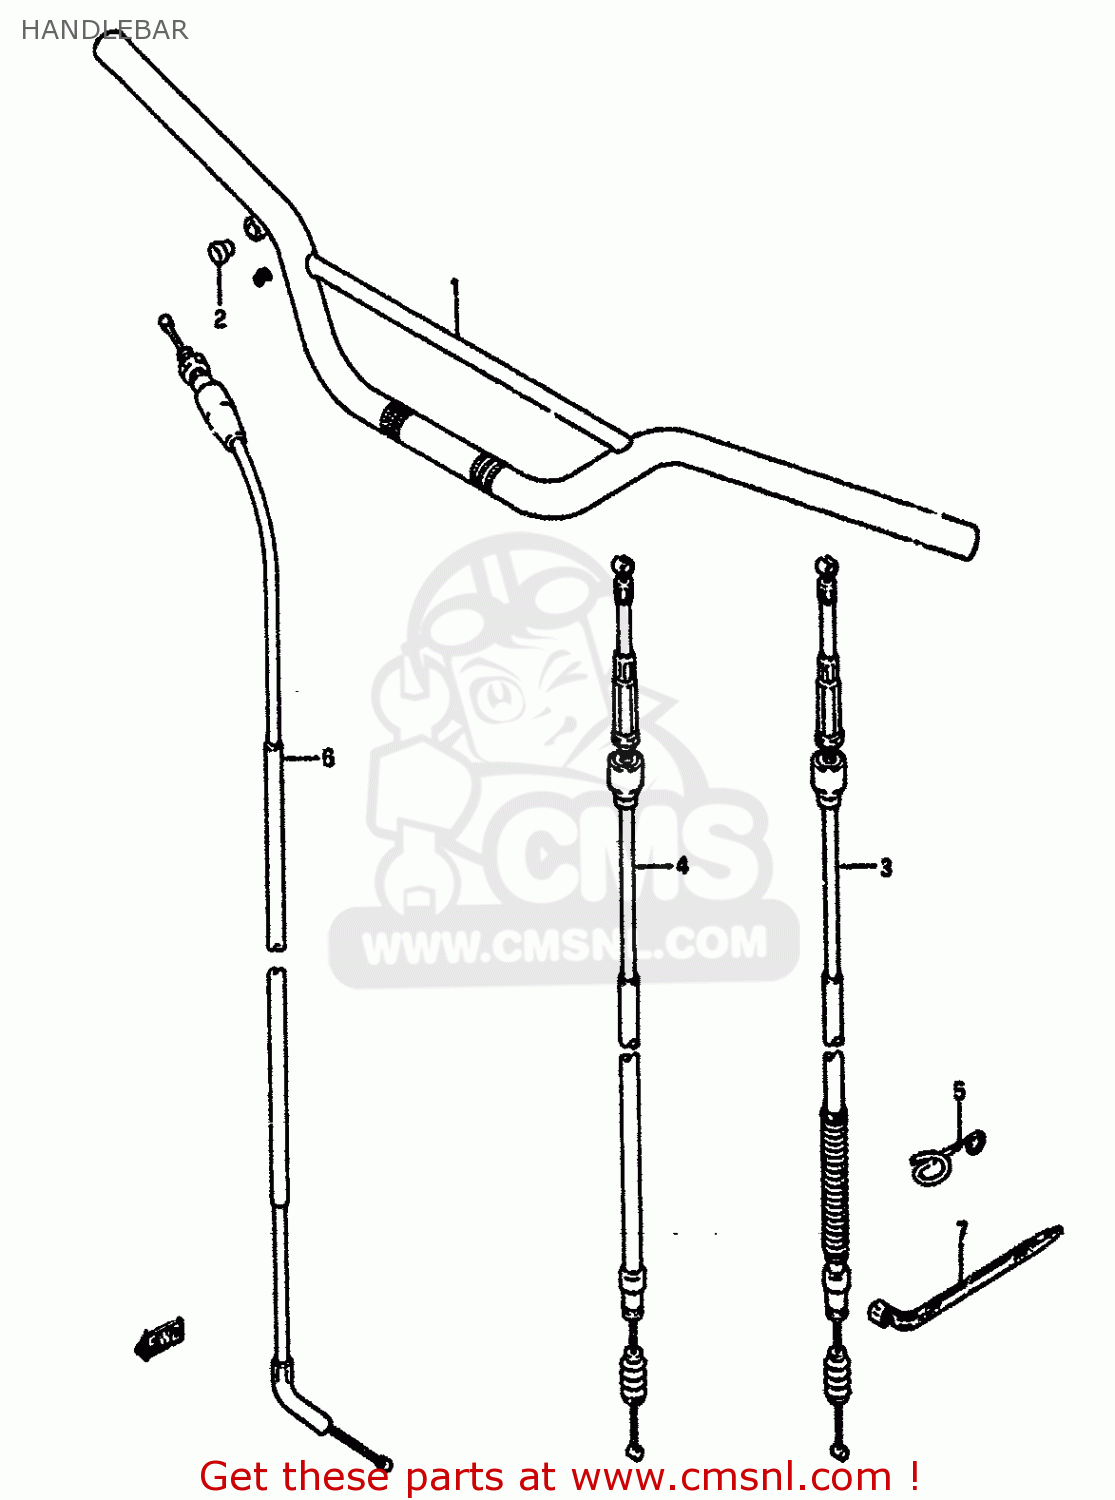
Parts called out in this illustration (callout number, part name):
1	HANDLEBAR
2	CAP(OD:14)
3	CABLE ASSY,CLUTCH
4	CABLE ASSEMBLY,CLUTCH
5	GUIDE,CLUTCH CABLE
6	CABLE ASSY,THROTTLE
7	CLAMP(L:125)
